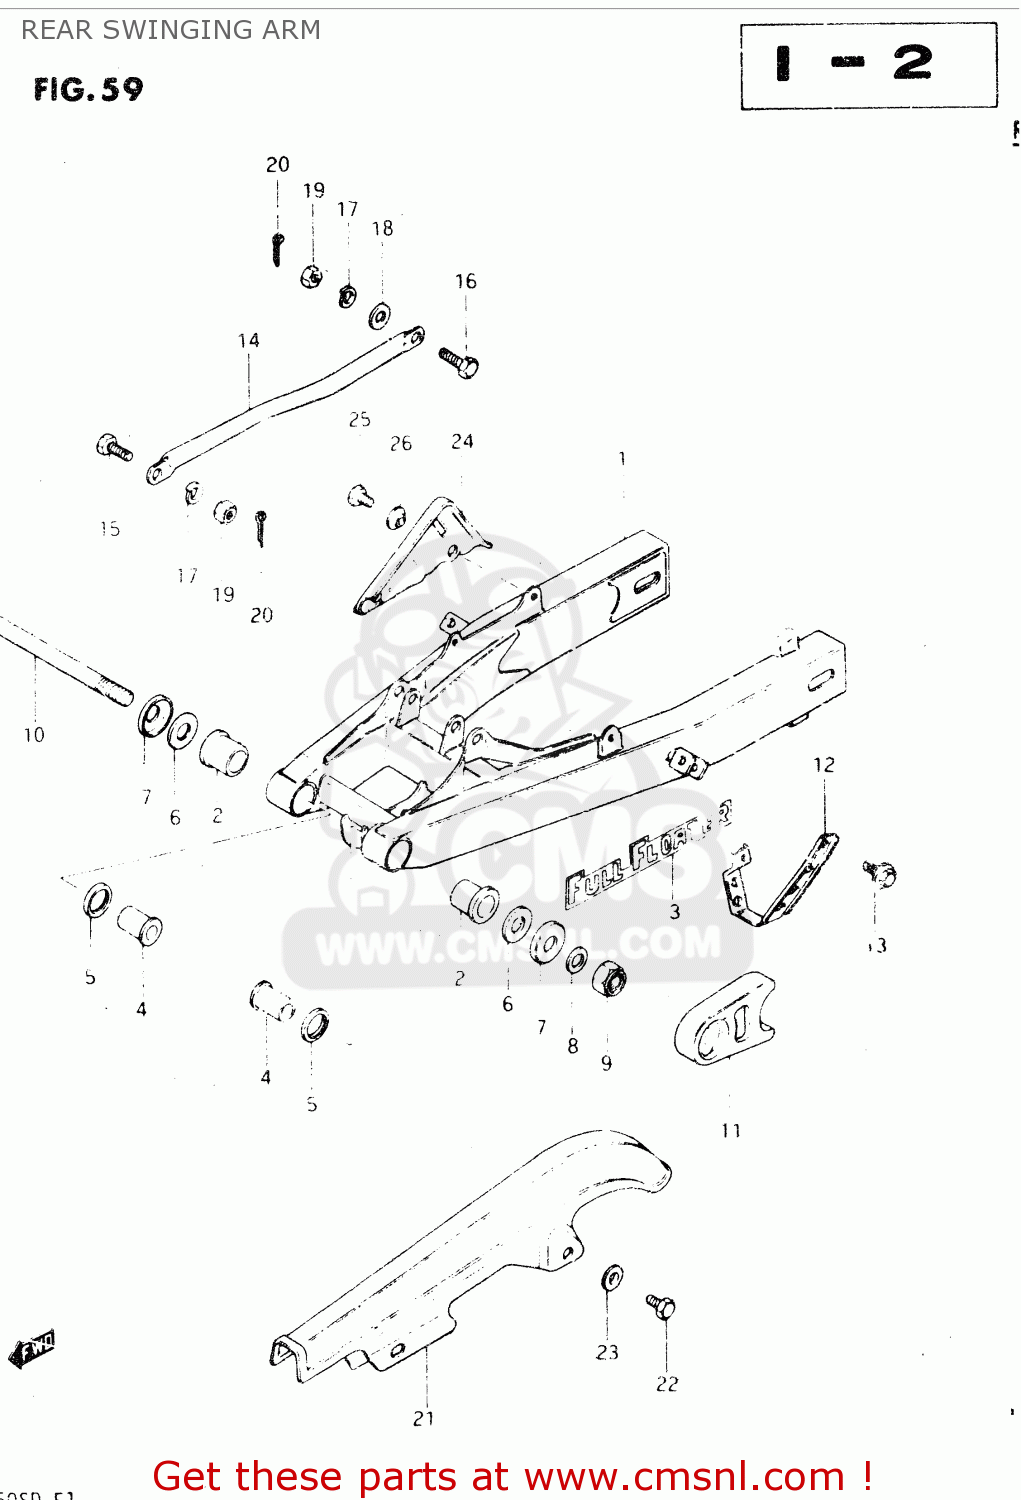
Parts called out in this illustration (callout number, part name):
1	SWINGING ARM, REAR
2	BUSHING,RR SWGARM PIVOT
3	EMBLEM
4	SPACER,RR SWGARM PIVOT OUTER
5	SEAL,OIL(20X27X5)
6	WASHER
7	COVER,REAR SWING ARM DUST
8	WASHER
9	NUT 14MM
10	SHAFT,REAR SWING ARM
11	BUFFER,CHAIN TOUCH DEFLECTOR
12	GUIDE,CHAIN
13	BOLT 8X12
14	LINK,REAR TORQUE
15	BOLT(8X22.5)
16	BOLT(8X26.5)
17	LOCK WASHER
18	WASHER
19	NUT
20	PIN 20X20
21	CASE,CHAIN
22	BOLT 6X8
23	WASHER
24	GUARD,PILLION FOOT
25	BOLT 6X8
26	WASHER
